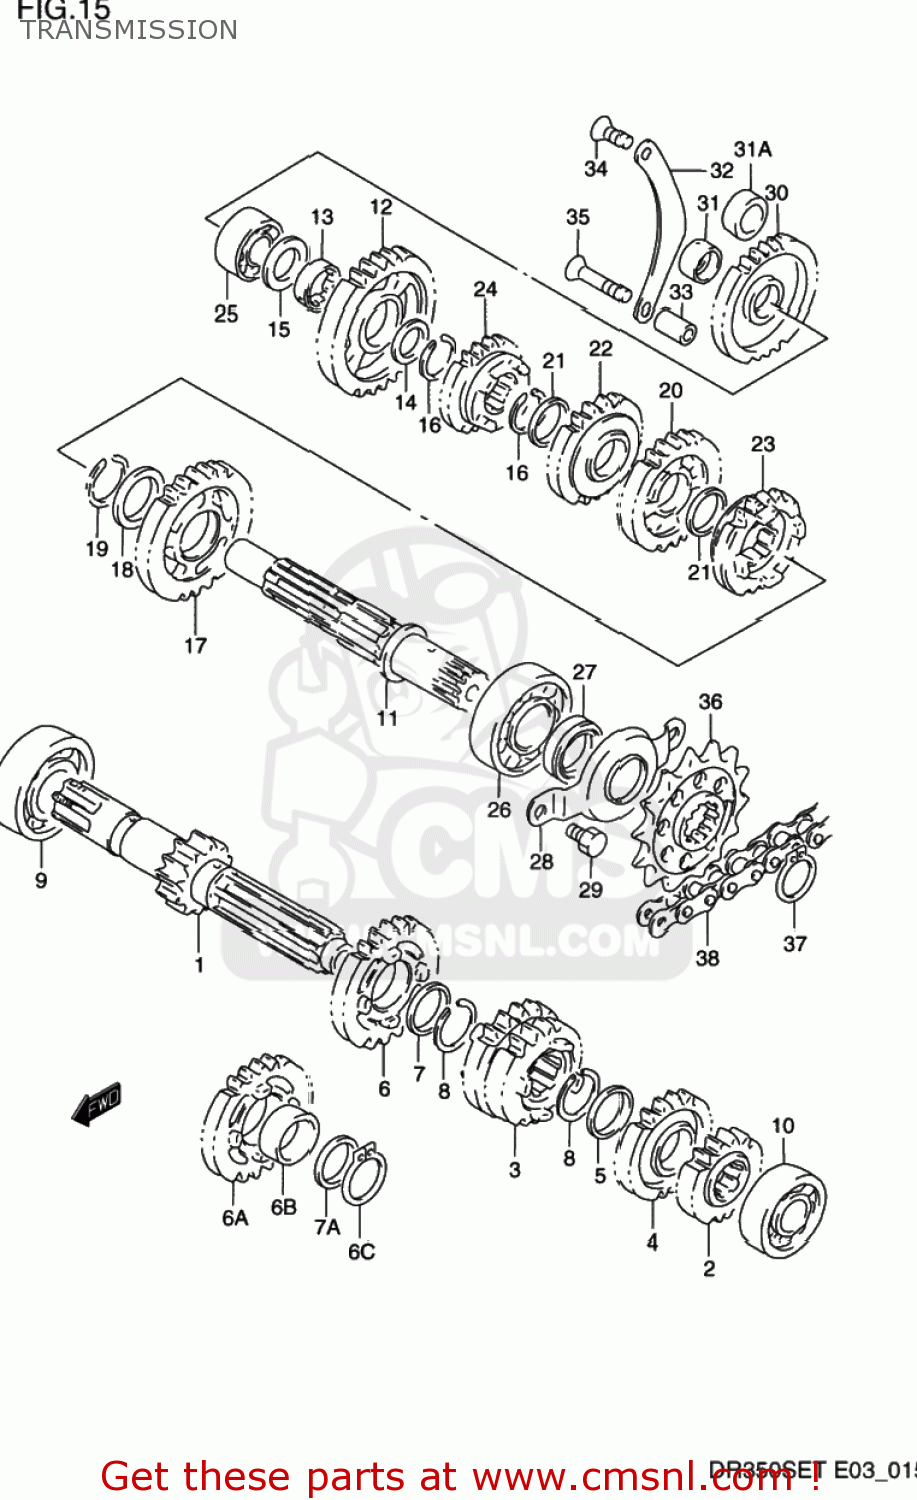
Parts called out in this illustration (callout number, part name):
1	SHAFT,COUNTER
2	GEAR,SECOND DRIVE (NT:15)
3	GEAR,3RD & 4TH DRIVE(NT:18/18)
4	GEAR,5TH DRIVE(NT:21)
5	WASHER
6	GEAR COMP,SIXTH DRIVE
6A	GEAR,6TH DRIVE(NT:23)
6B	BUSH(22X26X9)
6C	CIRCLIP
7	SHIM
7A	WASHER,THRUST
8	CIRCLIP
9	BEARING
10	BEARING
11	SHAFT,DRIVE
12	GEAR,1ST DRIVEN(NT:30)
13	BUSH,1ST DRIVEN GEAR
14	WASHER
15	WASHER,THRUST
16	CIRCLIP
17	GEAR,2ND DRIVEN(NT:26)
18	WASHER
19	CIRCLIP
20	GEAR,THIRD DRIVEN
21	SHIM
22	GEAR,4TH DRIVEN(NT:20)
23	GEAR,FIFTH DRIVEN (NT:20)
24	GEAR,SIXTH DRIVEN
25	BEARING(17X40X17.5)
26	BEARING(22X56X16)
27	SEAL,OIL(22X34X7)
28	RETAINER,DRIVE SHAFT OIL SEAL
29	BOLT
30	GEAR,KICK STARTER IDLE(NT:27)
31	BUSH,KICK STARTER IDLE GEAR
31A	SPACER(17X25X10.5)
32	RETAINER,KICK IDLE GEAR
33	SPACER (6.5X12X21)
34	SCREW
35	SCREW
36	SPROCKET,ENGINE
37	CIRCLIP
38	CHAIN ASSEMBLY,DRIVE
